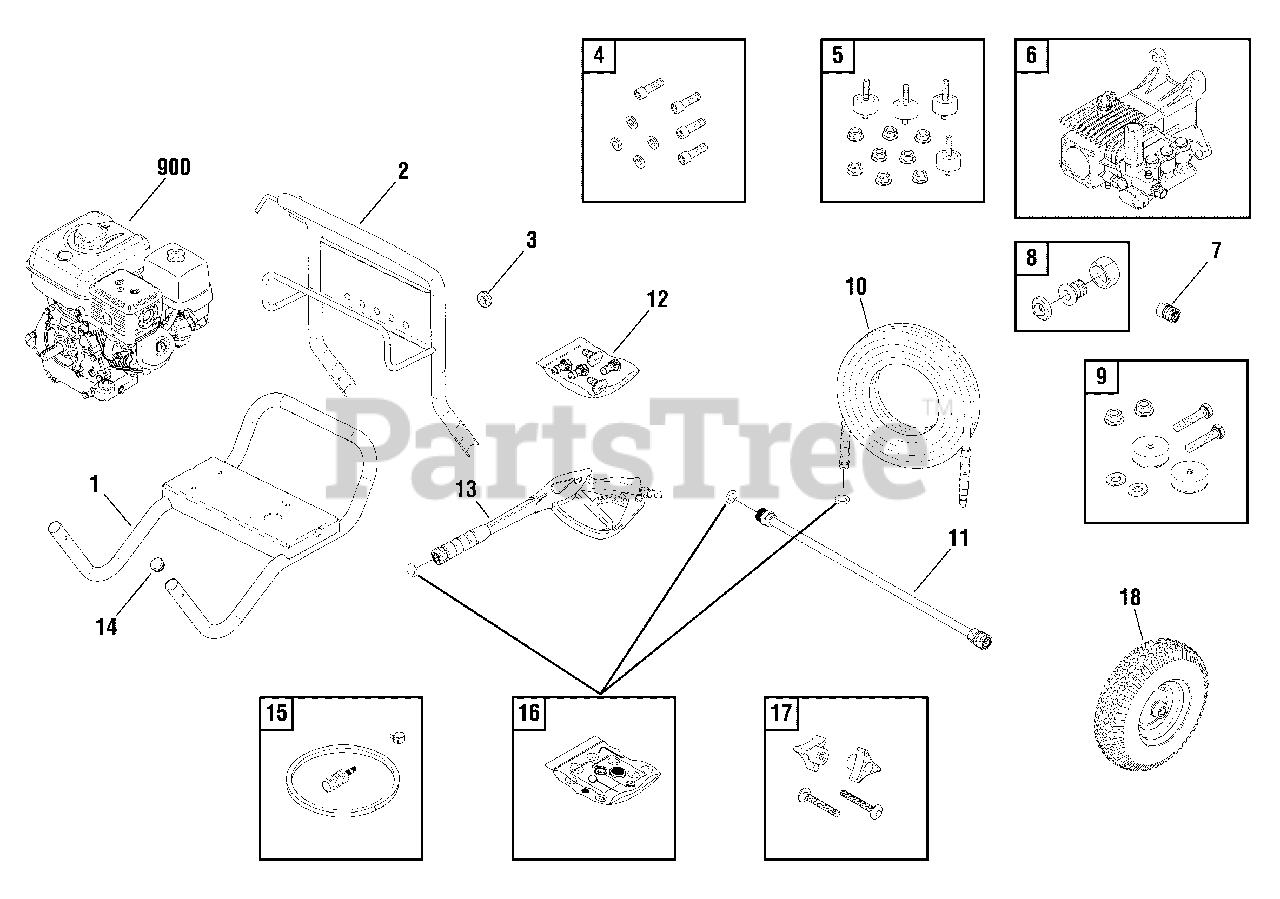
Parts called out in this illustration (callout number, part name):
4	KIT-HRDWR PUMP MOUNTING
5	KIT-HRDWR ENGINE MOUNTING
7	FITTING
8	ADAPTER-GARDEN HOSE
9	MOUNT-VIBRATION
11	EXTENSION-QC
12	KIT-QC NOZZLES
17	KIT-HARDWARE HANDLE
900	* ENGINE
